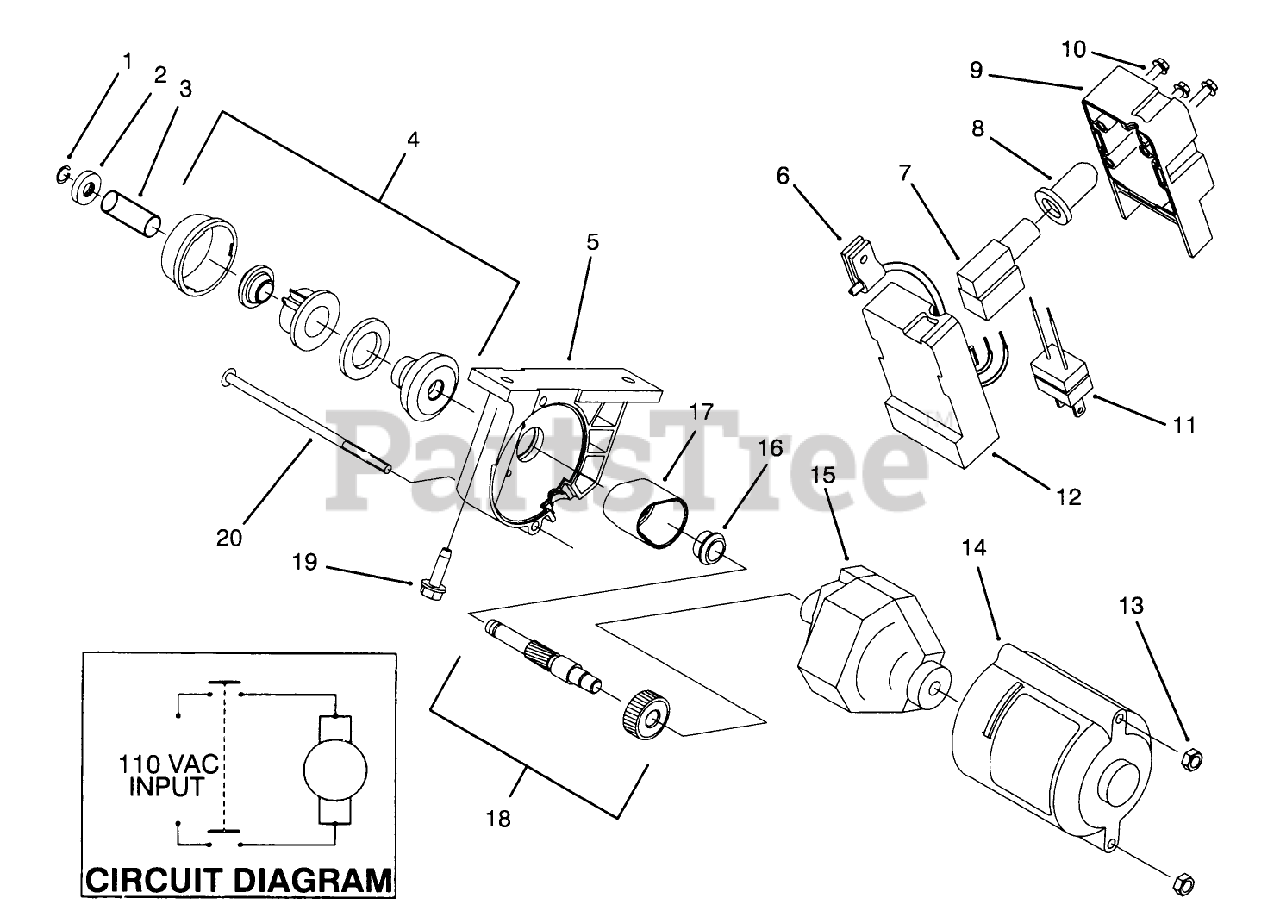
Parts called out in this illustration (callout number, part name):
1	RING-LOCK
2	PINION STOP
3	SPRING
4	Pinion ASM
5	HOUSING
6	CLAMP
7	SWITCH-STARTER
8	BOOT-SWITCH
9	Cap-Switch Housing
10	SCREW-PLASTITE
11	Plug
12	OBS BASE X
13	NUT-LOCK, NI
14	HOUSING - LOWER STARTER
15	STARTER MOTOR ASSEMBLY
16	BUSHING
17	COVER-GEAR
18	Asm-shaft & Gear
19	SCREW
